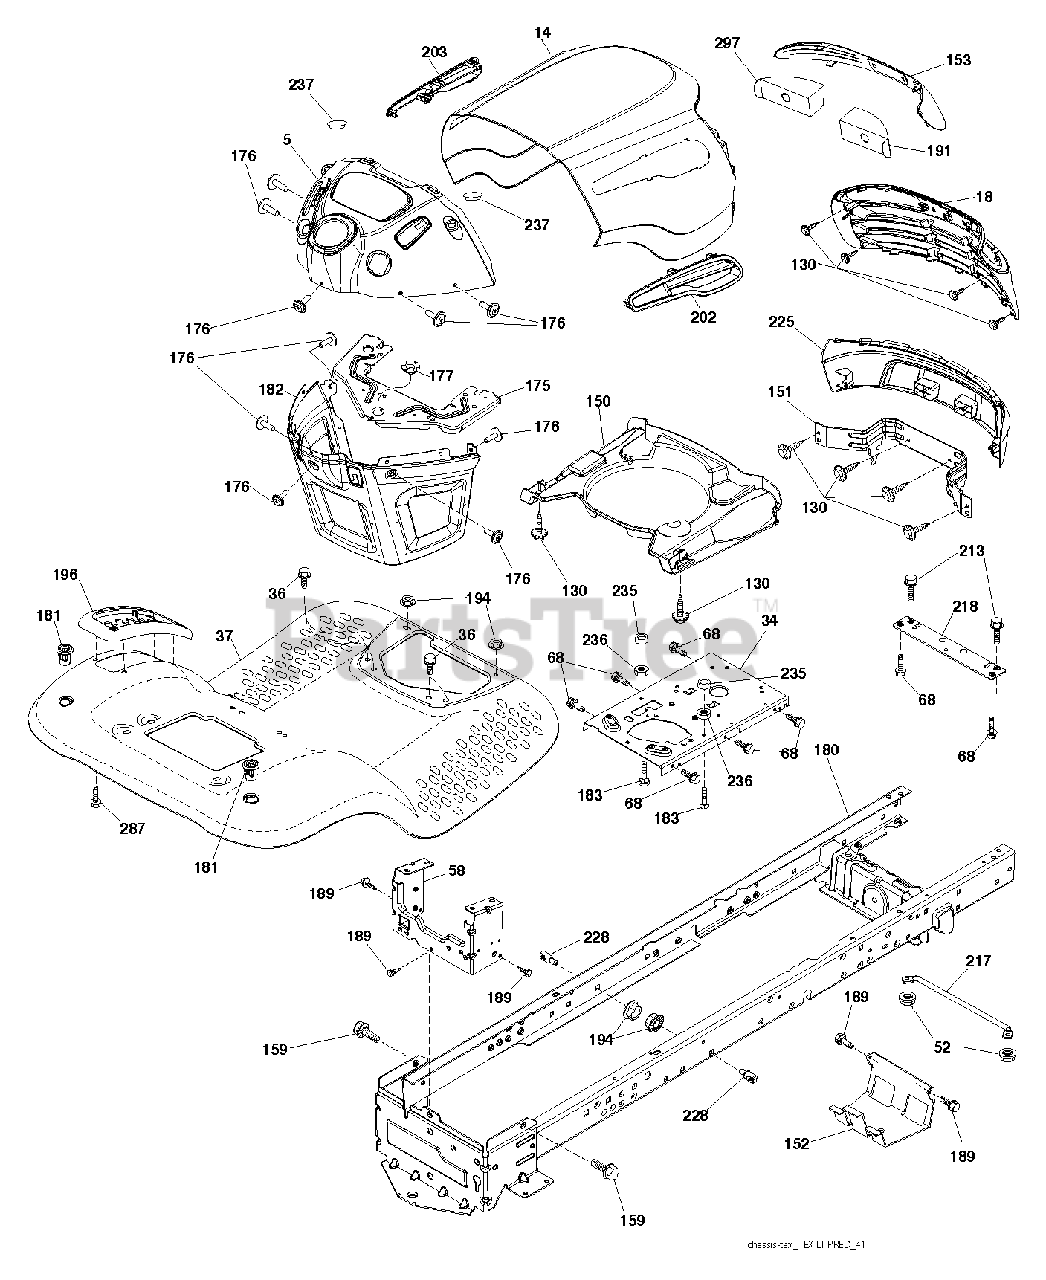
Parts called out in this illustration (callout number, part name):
34	PLATE.ENGINE.WELDED.CHASSIS
36	SCREW 5/16"
52	LOCKNUT
58	DRAWBAR UPPER 2PC SMALL FENDER
130	SCREW.#10 X 0.750.BOS THREAD
151	BRACKET.PIVOT.ALPHA.LT
152	SHIELD BROWNING
159	SCREW, 3/8-16X3/4
175	CROSSMEMBER
176	SCREW.#10-24X5/8.RN.QU
177	BUSHING STEERING
180	CHASS.WLDMNT.TL.12GA/2P.48/54
181	FEND/FTRST.PCH.CPH.NFW
182	DASH.LWER.PREDATOR/HUSQ.LT
183	BOLT.5/16-18X1-1/4 FULL THD
189	SCREW
191	INSERT.REFLECT.PREDATOR.LT.RH
194	NUT LOCK HEX FLANGE 5/16-18
196	CONSOLE.ASM.DECKLFT.BL/RBT.TLT
213	BOLT
217	ROD.PIVOT.HOOD
218	X-PIECE.HOOD.STOP.NON/
228	STUD.FASTNER.W/ANTI-ROTATE
235	SPACER FENDER
236	NUT.CENTERLOCK.5/16-
237	PLUG.MOUNT.CARGO.BLK
297	REFLECTOR.INSERT.PRED.LH.LT
